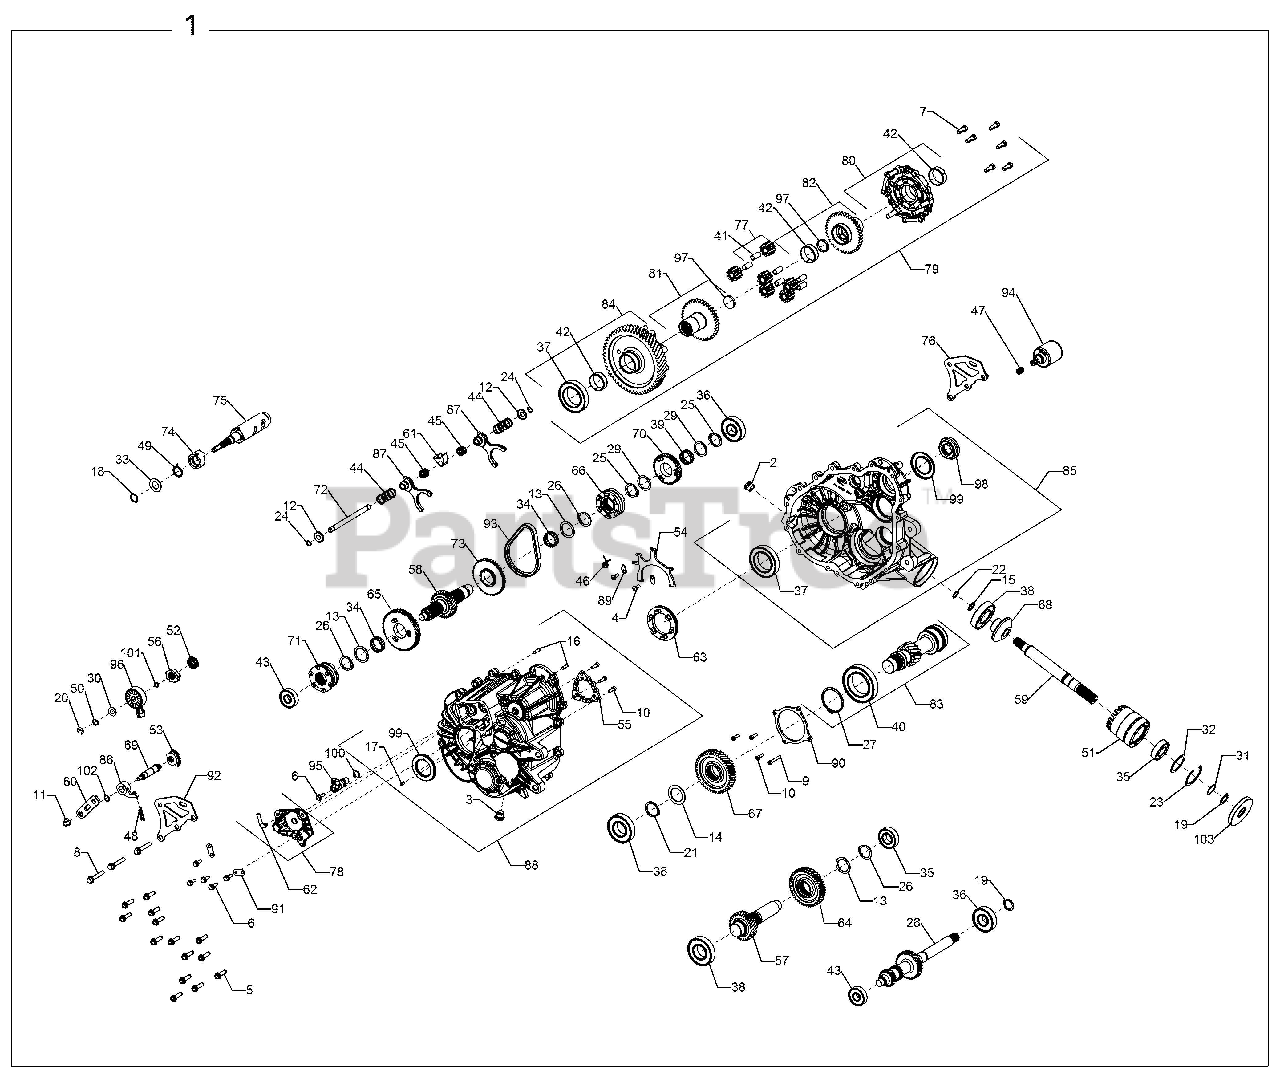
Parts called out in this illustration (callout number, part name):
1	ASM-GEARCASE,DIESEL,RGR
2	PLUG-SKT HD 1SO 6149,M18 X 1.5
3	PLUG-SOCKET HEAD W/MAG,M18X1.5
4	SCREW, TORX PAN HD M6 X 1 X 16
5	SCREW-HEXFLANGEHEAD,M8X1.25X30
7	SCREW-CAP HH,M8 X 1.25 X 20
9	SCR-M6X1.0X40,SOC/CAP(105344)
10	SCR-SCKT HD,CP,M6X1X18(105355)
11	NUT-M8X1.25,HXFLG,NYLN(110093)
12	WASHER-CUP
16	PIN, DOWEL, 6 X 20
17	SPRING-SLOTTED PIN,6MM
18	RING, RETAINING BASIC EXTERNAL
19	RING, SNAP
20	RING-RETAINING
21	RING,RETAINING
22	RING,RETAINING,EXTERNAL SHR-66
23	RING,RETAININGBASICINTRNL2.047
24	RING-RETAINING
25	RING,RETAINING
26	RING, RETAINING, EXTERNAL
27	RING, RETAINING
28	SHAFT, INPUT, HELICAL
29	WASHER,THRUST
30	WASHER,THRUST,.446X.88X.025
31	SHIM 1.180 X .995
32	SHIM 2.040 OD X 1.630 ID
33	SPACER, 19.4 X 34 X 2
34	BEARING,NEEDLE
37	BEARING, BALL
38	BEARING-BALL
39	BEARING,NEEDLE
40	BEARING, BALL
41	SCREW, TORX PAN HD M6 X 1 X 16
42	PLAIN,BEARING 40X44X15
43	BEARING, BALL
44	SPRING-COMPRESSION
45	SPRING-COMPRESSION
46	SPRING, TORSION RETURN
47	SPRING,COMPRSSN.54ODX.44IDX.05
48	SPRING, COMPRESSION DETENT
49	SPRING, TORSION
50	WASHER-SPRING,210393
51	TUBE, SNORKLE MACH
52	GEAR-SECTOR,16T
53	GEAR-SECTOR,31T-CUT TO 11T
54	SHIFT FORK (270507)
55	PARK PLATE (270509)
56	STAR, DETENT
57	SHAFT, IDLER, 29T
58	SHAFT, REVERSE, 29T
59	SHAFT, OUTPUT, FRONT
60	BELLCRANK
61	COLLAR-SHIFT
62	TUBE-VENT,90-1/4" HOSE
63	DOG-ENGAGEMENT
64	GEAR, 44T, STAGE 2
65	GEAR-LOW,67T(352856)
66	DOG, ENGAGEMENT, 6-FACE
67	GEAR, 46T, STAGE 3
68	GEAR-13T,FRONT OUTPUT(352957)
69	SHAFT, SHIFT
70	GEAR 49T
71	SHIFT DOG, PARK/LOW (353357)
72	RAIL-SHIFT SHAFT(353622)
73	SPROCKET, 48T, 6-FACE
74	PARK CAM
75	DRUM, SHIFT MACH
76	WELD-REAR MOUNT BRKT
77	GEAR SUBASSEMBLY
78	SUBASSY COVER, SECTOR GEARS
79	DIFF-LOCKING (411600)
80	SUBASSY-COVER,DIFF (411601)
81	SUBASSY-GEAR,39T SIDE (411607)
82	SUBASSY-GEAR,39T SIDE (411608)
83	ASM-SUB,PINION SHAFT(411759)
84	SUBASSY-GEAR,53T (411797)
85	SUBASSY,LH CASE(411919)
86	ROLLER PAWL
87	SUBASSEMBLY, SHIFT FORK
88	SUBASSEMBLY RH COVER
89	RETAINER-FORK
90	COVER, BEARING, CENTER DRIVE
91	BRKT-MOUNT(430592)
92	BRKT-REAR MOUNT
93	CHAIN, SILENT
94	SOLENOID
95	SENSOR-SPEED,TRANS
96	SWITCH, ROTARY 2 PIN RESISTIVE
97	PLUG,EXPANSION,1 1/4
99	SEAL-TRIPLE LIP,VITON,40X70X7
100	O-RING, -113
103	SEAL-TRIPLE LIP 25X80X10
